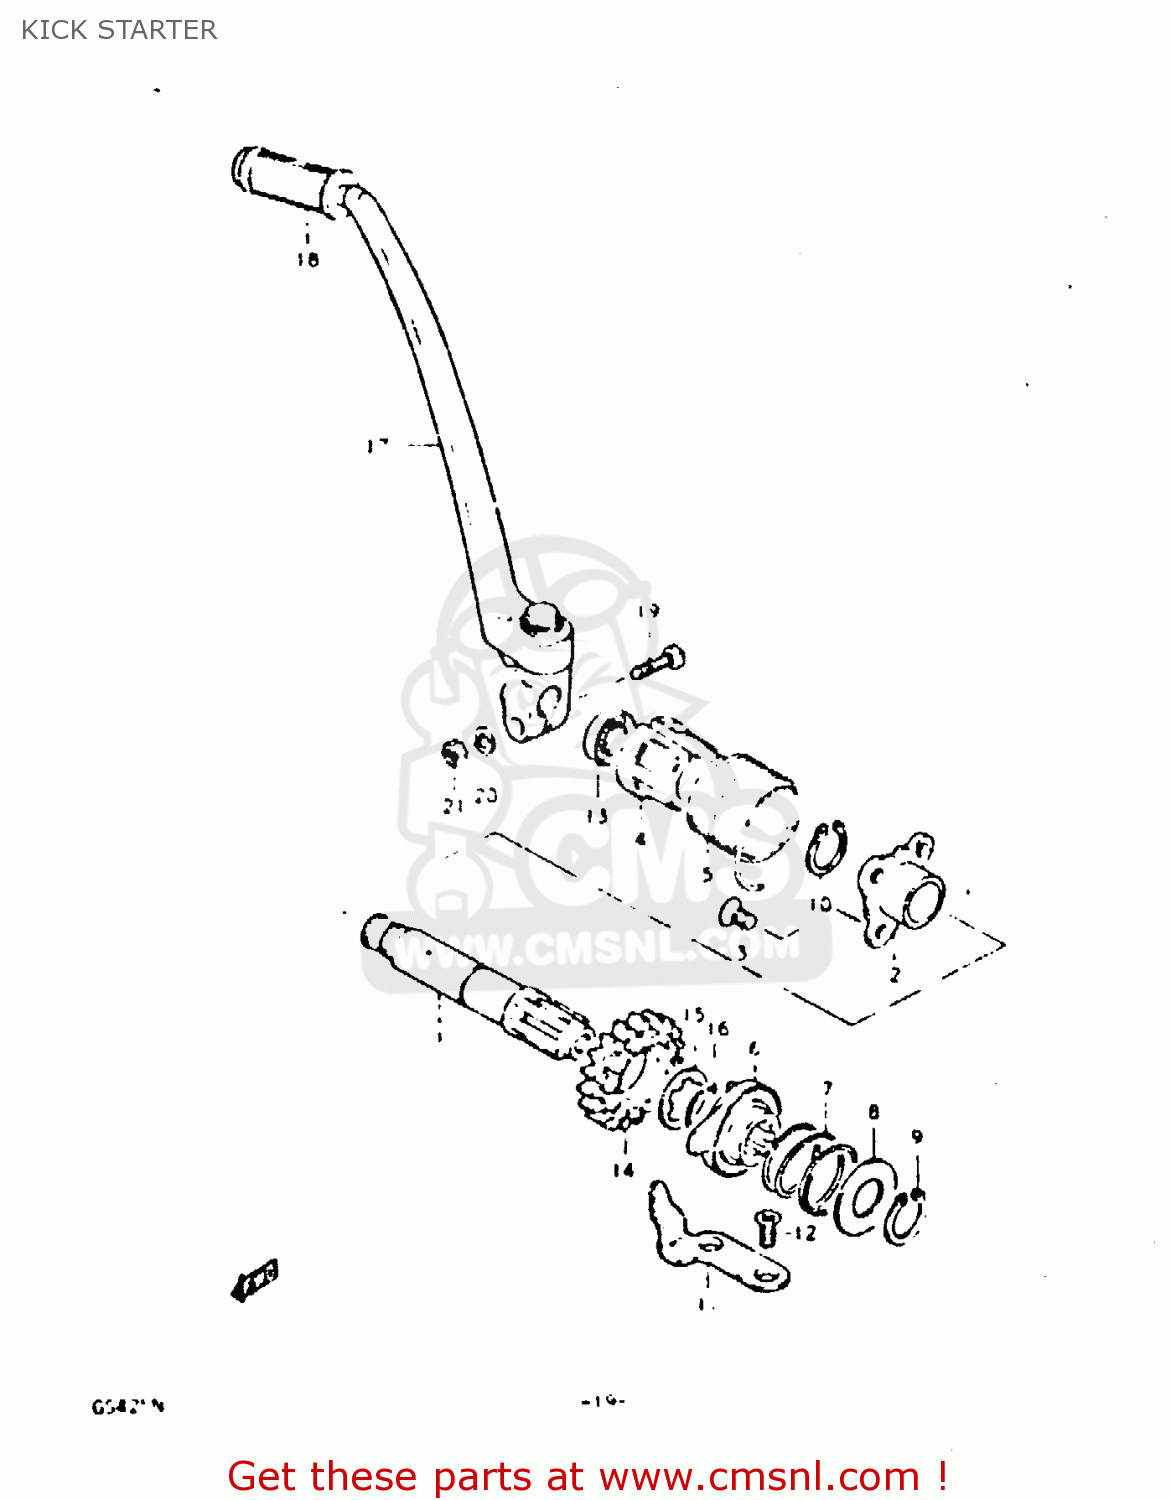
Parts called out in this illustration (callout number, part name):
1	SHAFT,KICK STARTER
2	HOLDER,KICK STARTER SHAFT
3	SCREW
4	GUIDE,STARTER SHAFT SPRING
5	SPRING
6	STARTER,KICK
7	SPRING
8	WASHER
9	CIRCLIP
10	CIRCLIP
11	GUIDE,STARTING SPRING
12	SCREW
13	SEAL,OIL(20X27X5)
14	GEAR,KICK STARTER DRIVE
15	WASHER,LOCK
16	CIRCLIP
17	LEVER ASSY,KICK STARTER
18	RUBBER,KICK STARTER PEDAL
19	BOLT,M10X1.25X
20	LOCK WASHER
21	NUT
